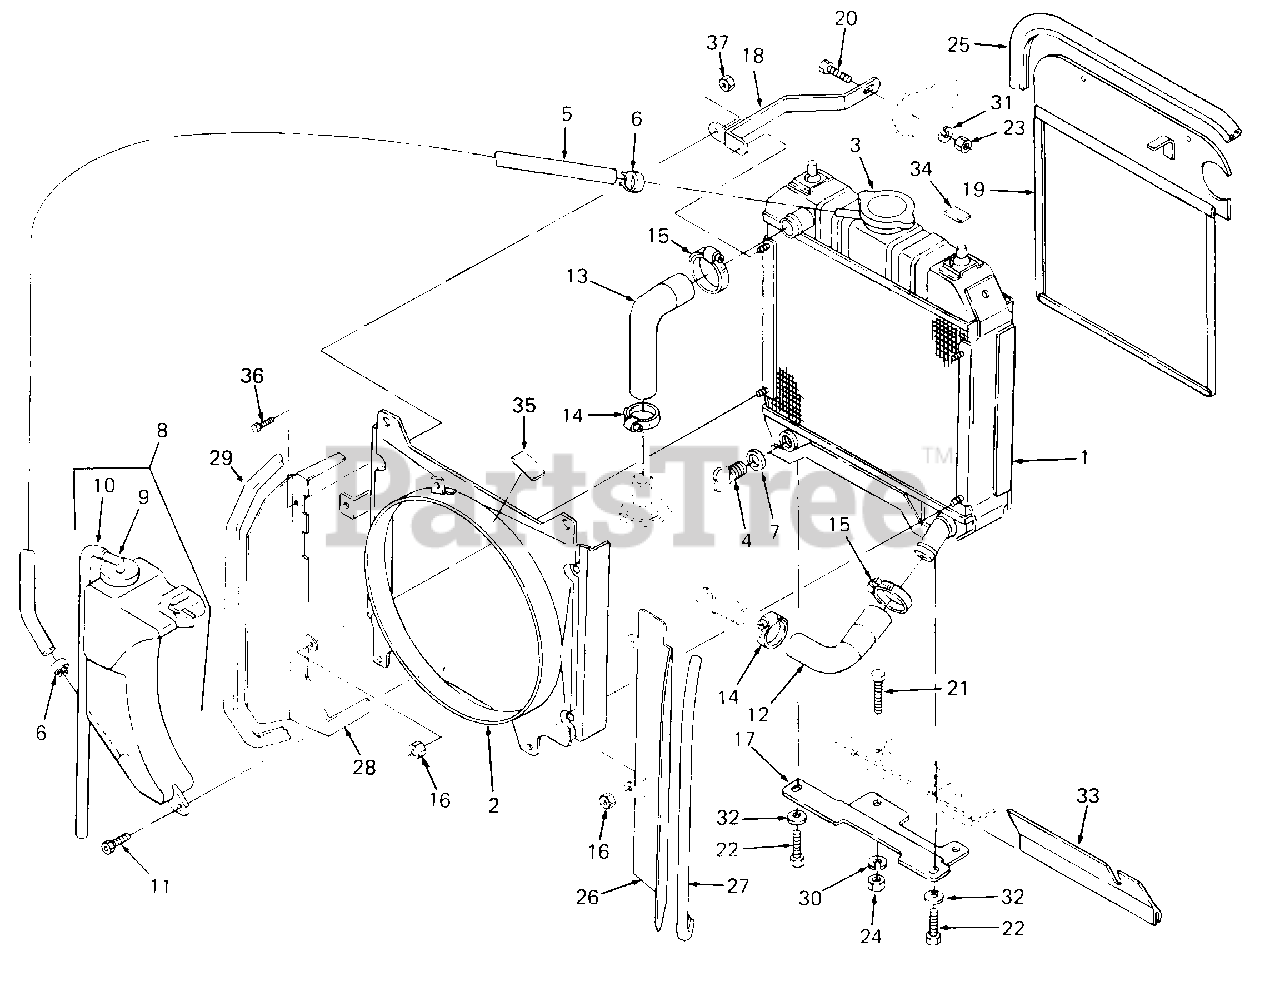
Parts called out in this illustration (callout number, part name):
1	Radiator Assy
5	Pipe, Water Overflow
8	Tank Assy, Reserve
10	Pipe, Overflow
17	Mount, Radiator
18	Brace, Radiator
19	Heat Baffle Assy
20	Screw, Hex Cap, 1/4-20 X .62 Lg GR5
21	Screw, Hex Cap, 5/16-18 X .75 Lg GR5
22	Screw, Hex Cap, M10 X 1.25 X 25 mm Lg GR8
23	Nut, Hex, 1/4-20 GR5
24	Nut, Hex, 5/16-18 GR5
25	Seal, Baffle, 17" Lg
26	Baffle, Radiator LH
27	Seal, Baffle, 15" Lg
28	Baffle, Radiator RH
29	Seal, Baffle, 16" Lg
30	Washer, Lock, 5/16 Dia
31	Washer, Lock, 1/4 Dia
32	Washer, Bell, .45 X 1.0 X.062
33	Flap, Radiator Bottom
34	Label, Radiator
35	Label, Radiator
36	Screw, Hex Cap, 1/4-20 X.375 Lg
37	Nut, Hex Center Lock, 1/4-20
